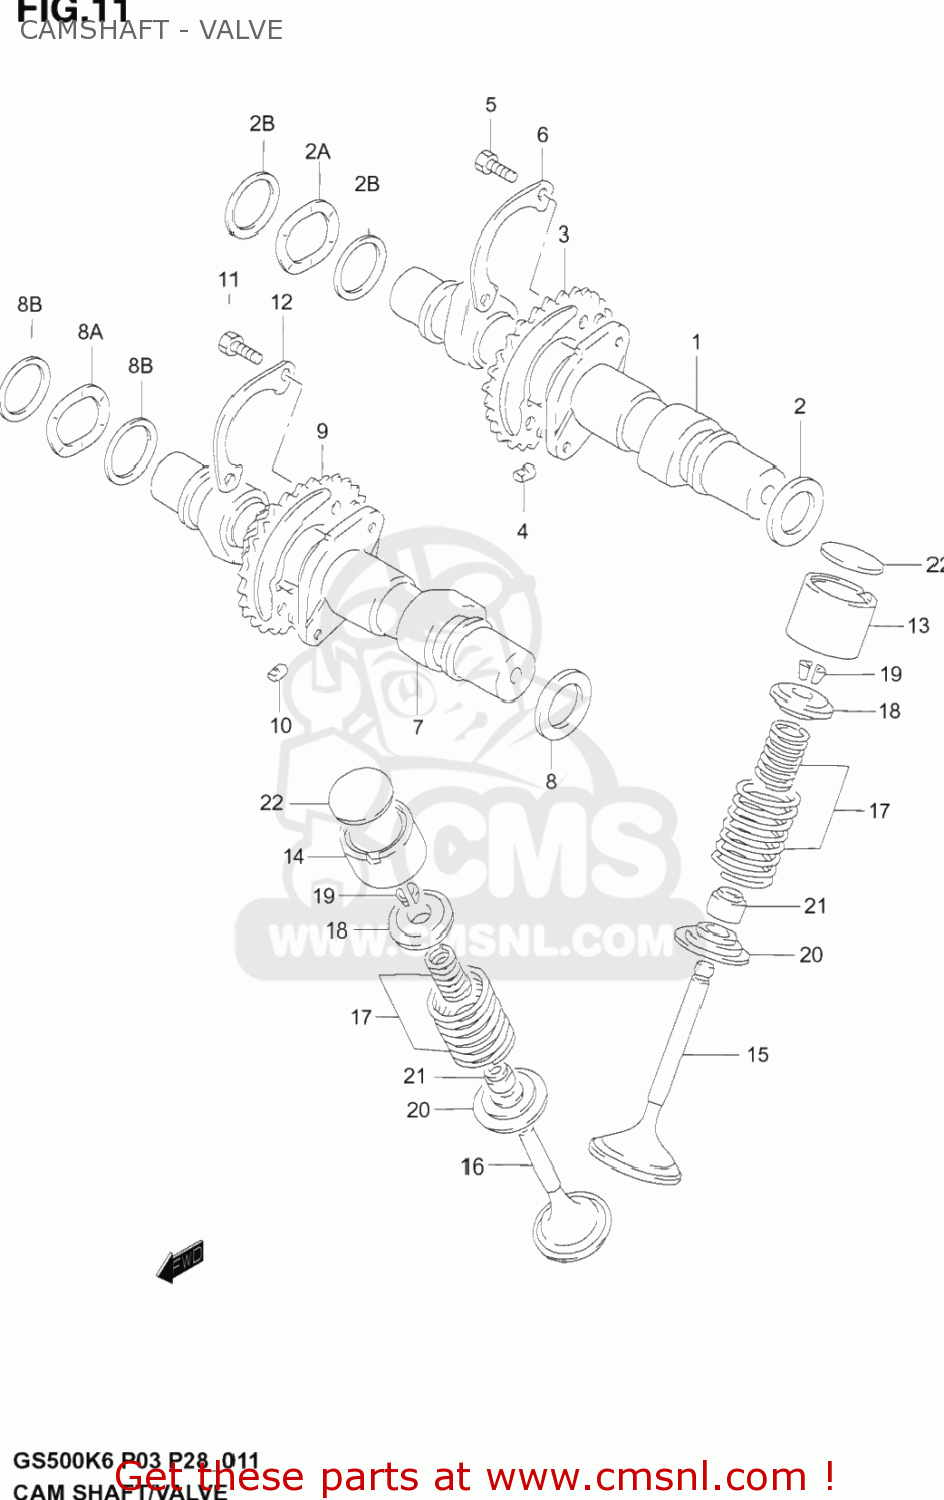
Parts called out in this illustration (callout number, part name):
1	CAMSHAFT SET,INTAKE
2	SHIM(22X30X1)
2A	WASHER
2B	SHIM(22X28X0.7)
3	SPROCKET,CAMSHAFT INTAKE
4	PIN,SPROCKET
5	BOLT(6X12.5)
6	WASHER,CAM CHAIN SPROCKET
7	CAMSHAFT SET,EXHAUST
8	SHIM(22X30X1)
8A	WASHER
8B	SHIM(22X28X0.7)
9	SPROCKET,EXHAUST CAM(NT:30)
10	PIN,SPROCKET
11	BOLT(6X12.5)
12	WASHER,CAM CHAIN SPROCKET
13	TAPPET
14	TAPPET,INTAKE
15	VALVE,INTAKE
16	VALVE,EXHAUST
17	SPRING SET,VALVE
18	RETAINER,VALVE SPRING
19	COTTER VALVE
20	SEAT,VALVE SPRING
21	SEAL,OIL(7X14.4X9)
22	SHIM,TAPPET(T:2.15)
